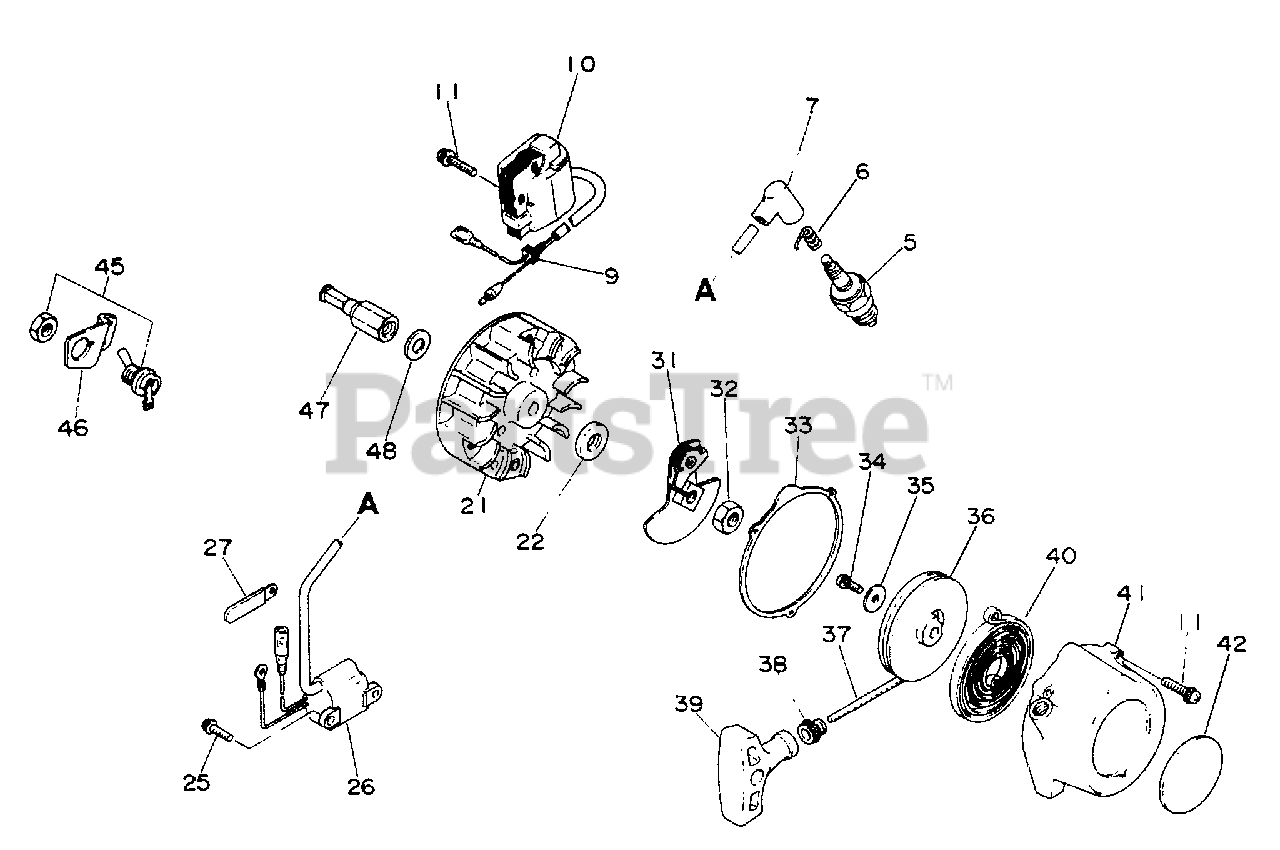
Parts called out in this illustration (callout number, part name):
5	SPARK PLUG -- CJ-8
6	TERMINAL, SPARK PLUG CAP
7	CAP, SPARK PLUG
10	COIL, IGNITION
11	SCREW - 4X20
21	FLYWHEEL
25	SCREW - 4X14
26	COIL, IGNITION
27	CLIP
31	STARTER PAWL ASSY
33	GASKET, STARTER
34	SCREW - 4X10
36	REEL, ROPE
37	ROPE, STARTER - 3X850
38	GUIDE, ROPE
39	GRIP, STARTER
40	SPRING, REWIND
41	CASE, STARTER
42	LABEL - ECHO
45	IGNITION SWITCH KIT
46	BRACKET, SWITCH
47	DRIVESHAFT
48	WASHER - 8
